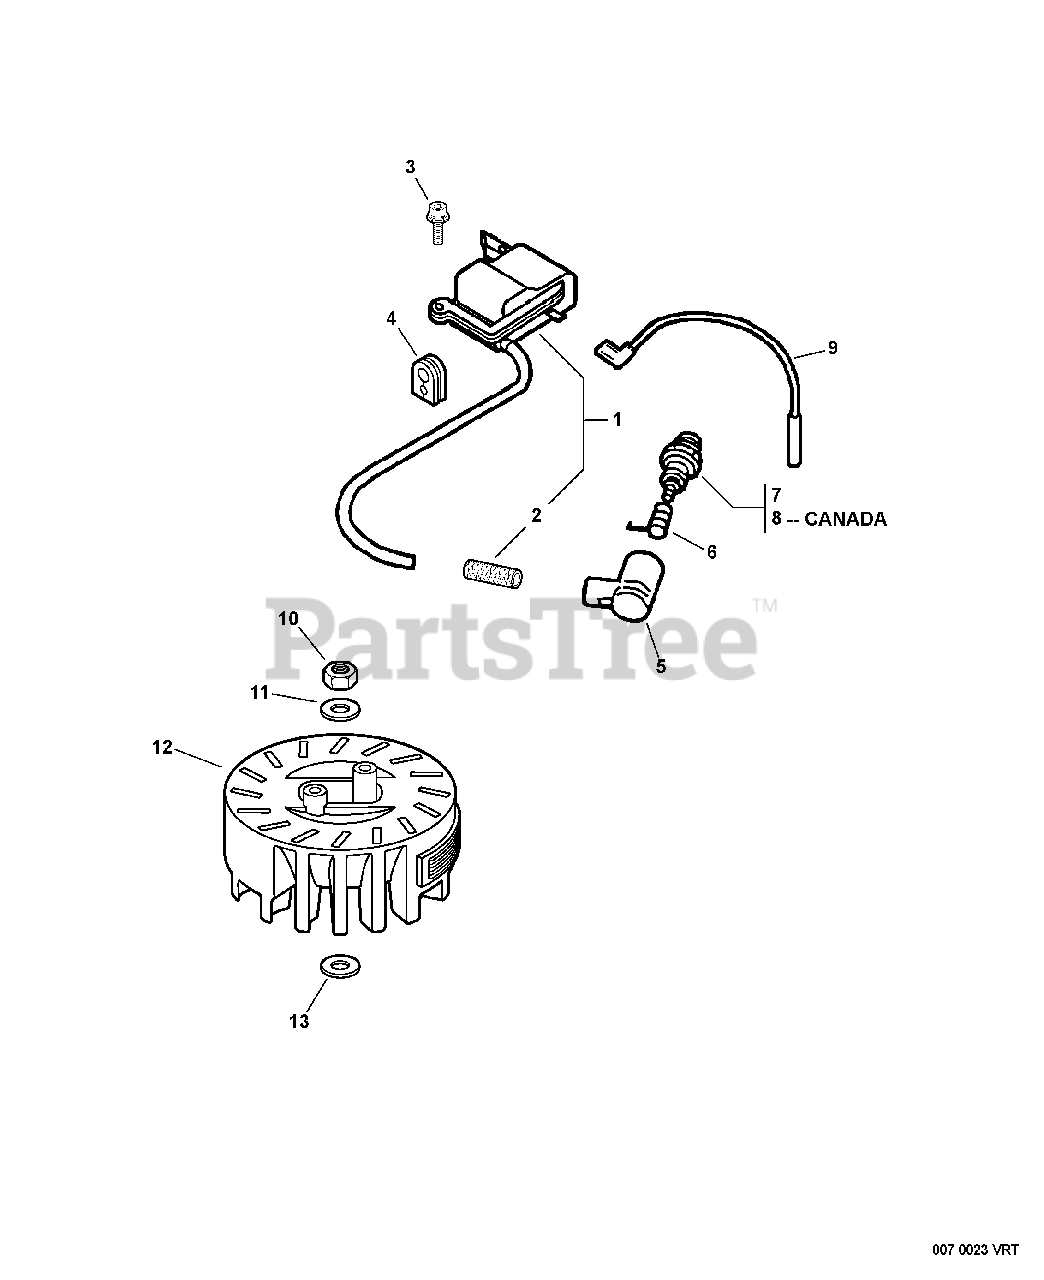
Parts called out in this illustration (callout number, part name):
1	COIL, IGNITION
2	TUBE, INSULATOR
3	SCREW - 5X16
5	CAP, SPARK PLUG
6	TERMINAL, SPARK PLUG CAP
7	SPARK PLUG -- BPM-8Y
8	SPARK PLUG -- BPMR-8Y
9	LEAD - GROUND
10	NUT - LEFT HAND
11	WASHER - 8
12	FLYWHEEL
13	WASHER, CLUTCH
14	RePower TUNE-UP KIT
15	RePower TUNE-UP KIT
